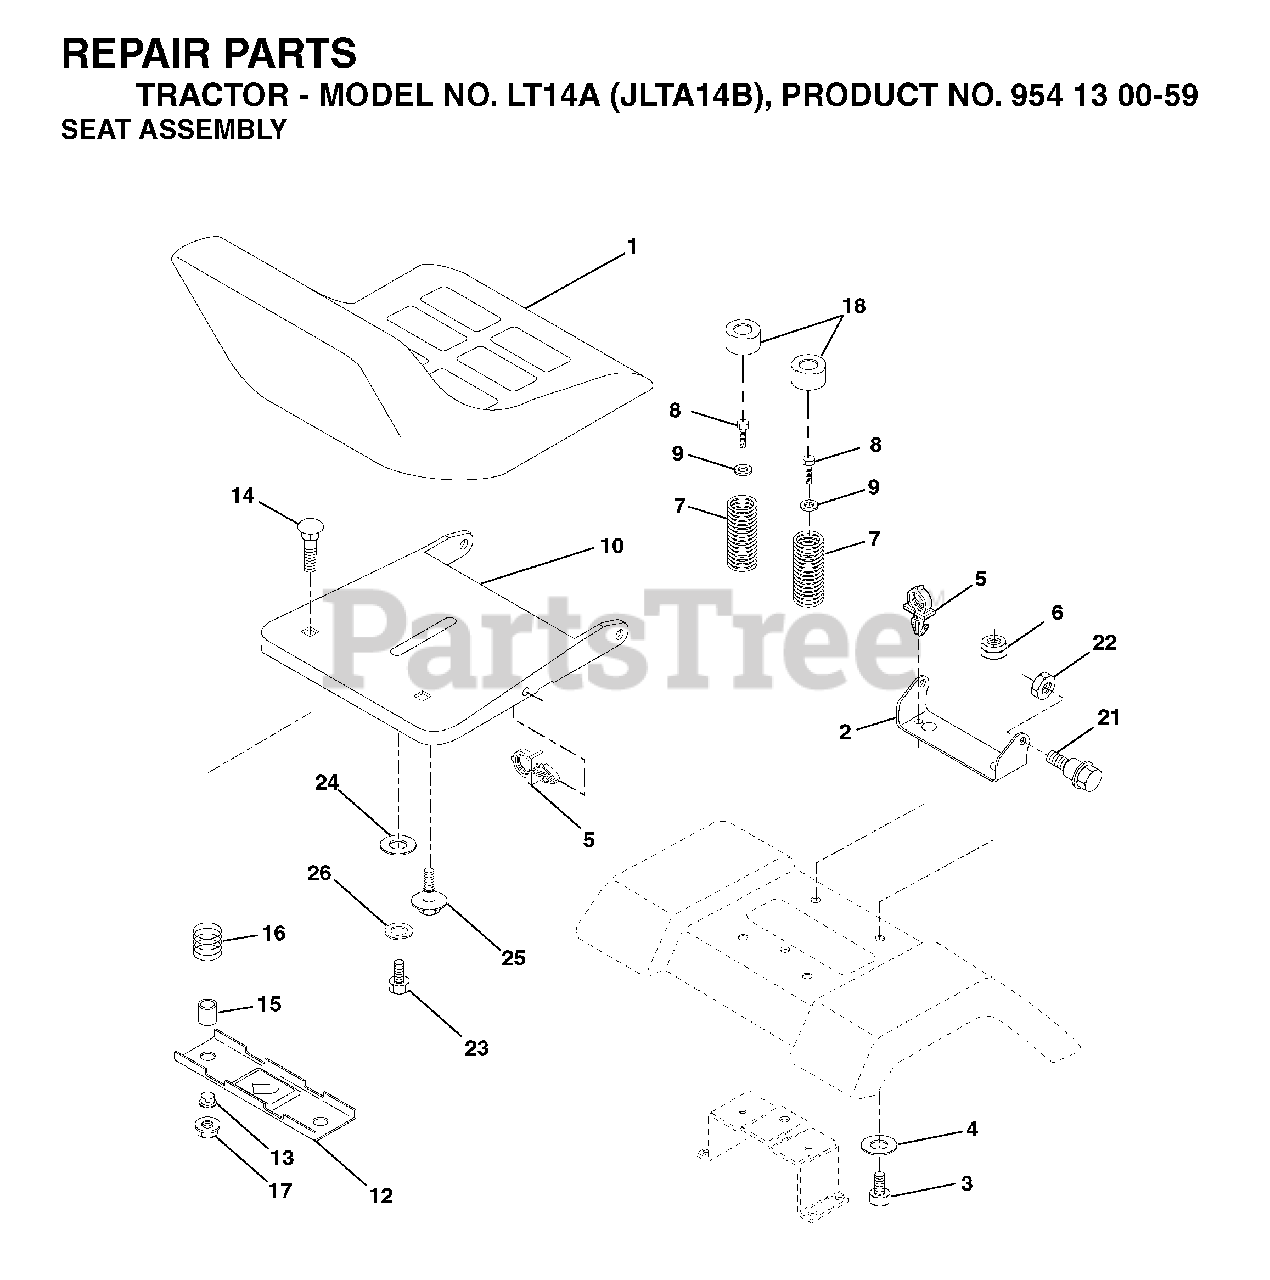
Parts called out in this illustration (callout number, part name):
2	SEAT PIVOT BRKT
4	WASHER PM
5	PUSH CLIP
6	NUT
7	SPRING COMPRESSION
8	SCREW 3/8-16X1
9	WASHER
10	PAN SEAT
12	BRKT SWITCH
14	BOLT.ROUND.HEAD.SQUARE.NECK
15	SPACER SPLIT 28X.96
17	NUT T
18	CAP SPRING
21	BOLT.SHOULDER.5/16-18
22	NUT.71038.31-18.HEX.NYLOCK
23	BOLT.HEX.BLACK
25	BOLT,SHOULD
26	LOCKWASHER
